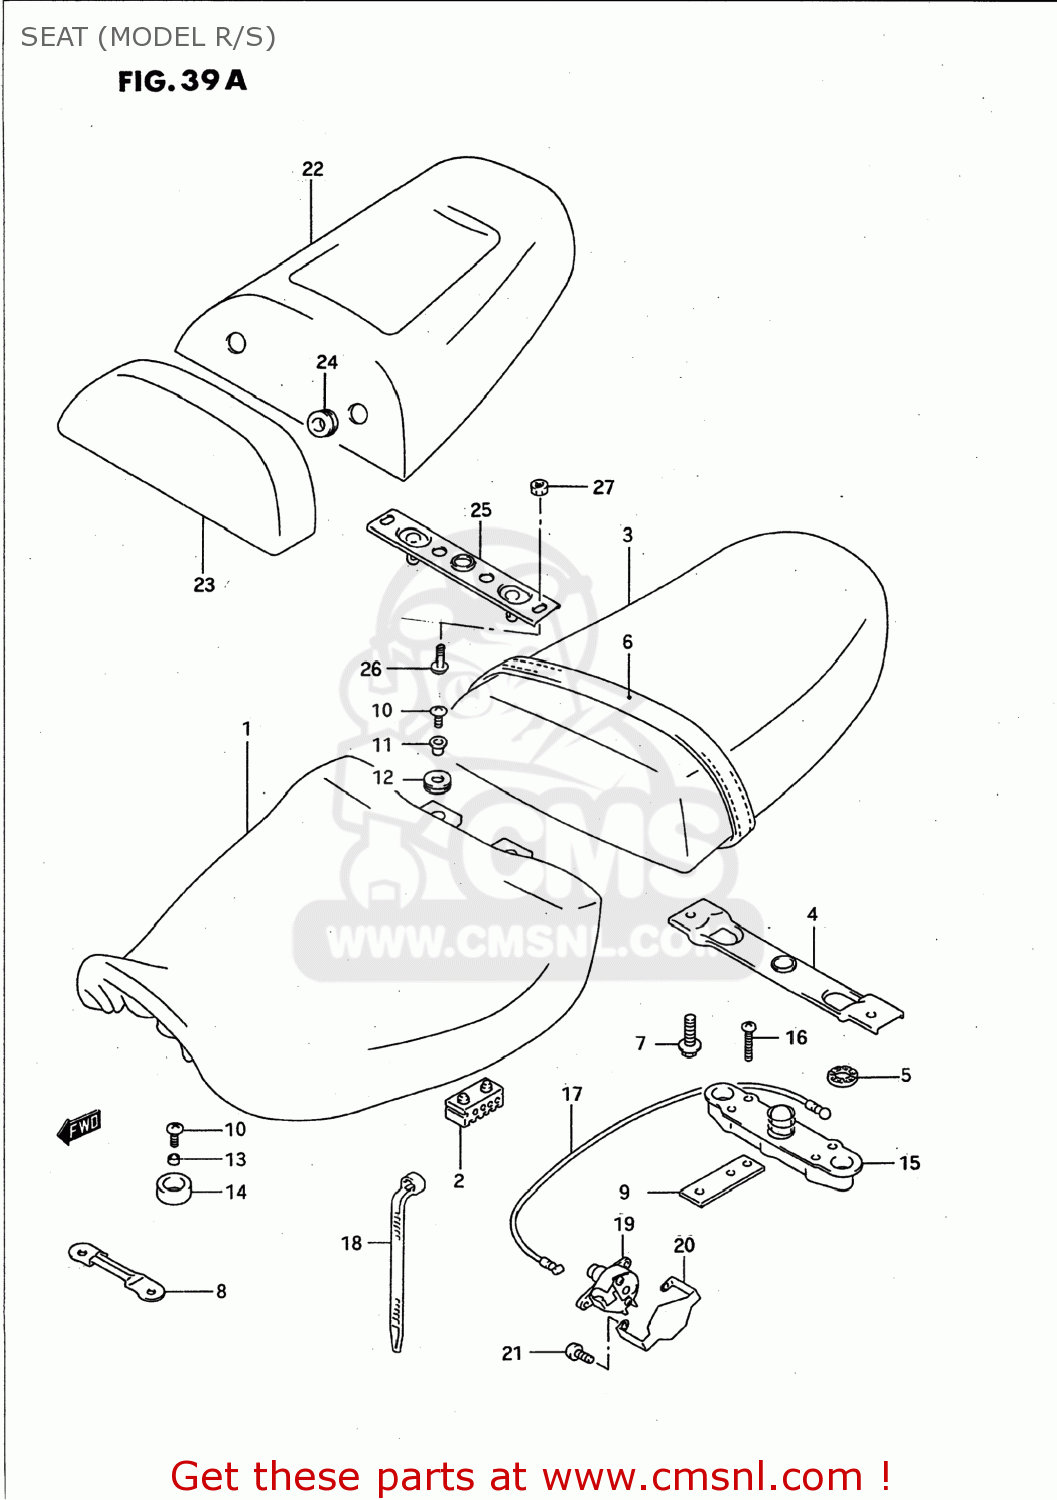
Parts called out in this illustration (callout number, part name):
1	SEAT ASSEMBLY
2	CUSHION,SEAT(40X20X15)
3	SEAT ASSEMBLY,PILLION
4	STRIKER,SEAT LOCK
5	CUSHION
6	BAND COMP,SEAT
7	BOLT
8	PLATE,SEAT FR HOOK
9	BRACKET COMP,SEAT SUPPORT
10	SCREW
11	WASHER
12	CUSHION
13	SPACER (6.8X10X4.7)
14	CUSHION,TAIL COVER UPR
15	LOCK ASSY,SEAT STRIKER
16	SCREW
17	CABLE,SEAT LOCK
18	CLAMP L:165
19	LOCK SET,SEAT
20	PLATE,SEAT LOCK GUARD
21	SCREW(6X12)
22	BOX SET,SEAT TAIL
23	BACKREST COMP,SEAT
24	CUSHION
25	STRIKER,SEAT LOCK
26	SCREW 6X12
27	NUT
